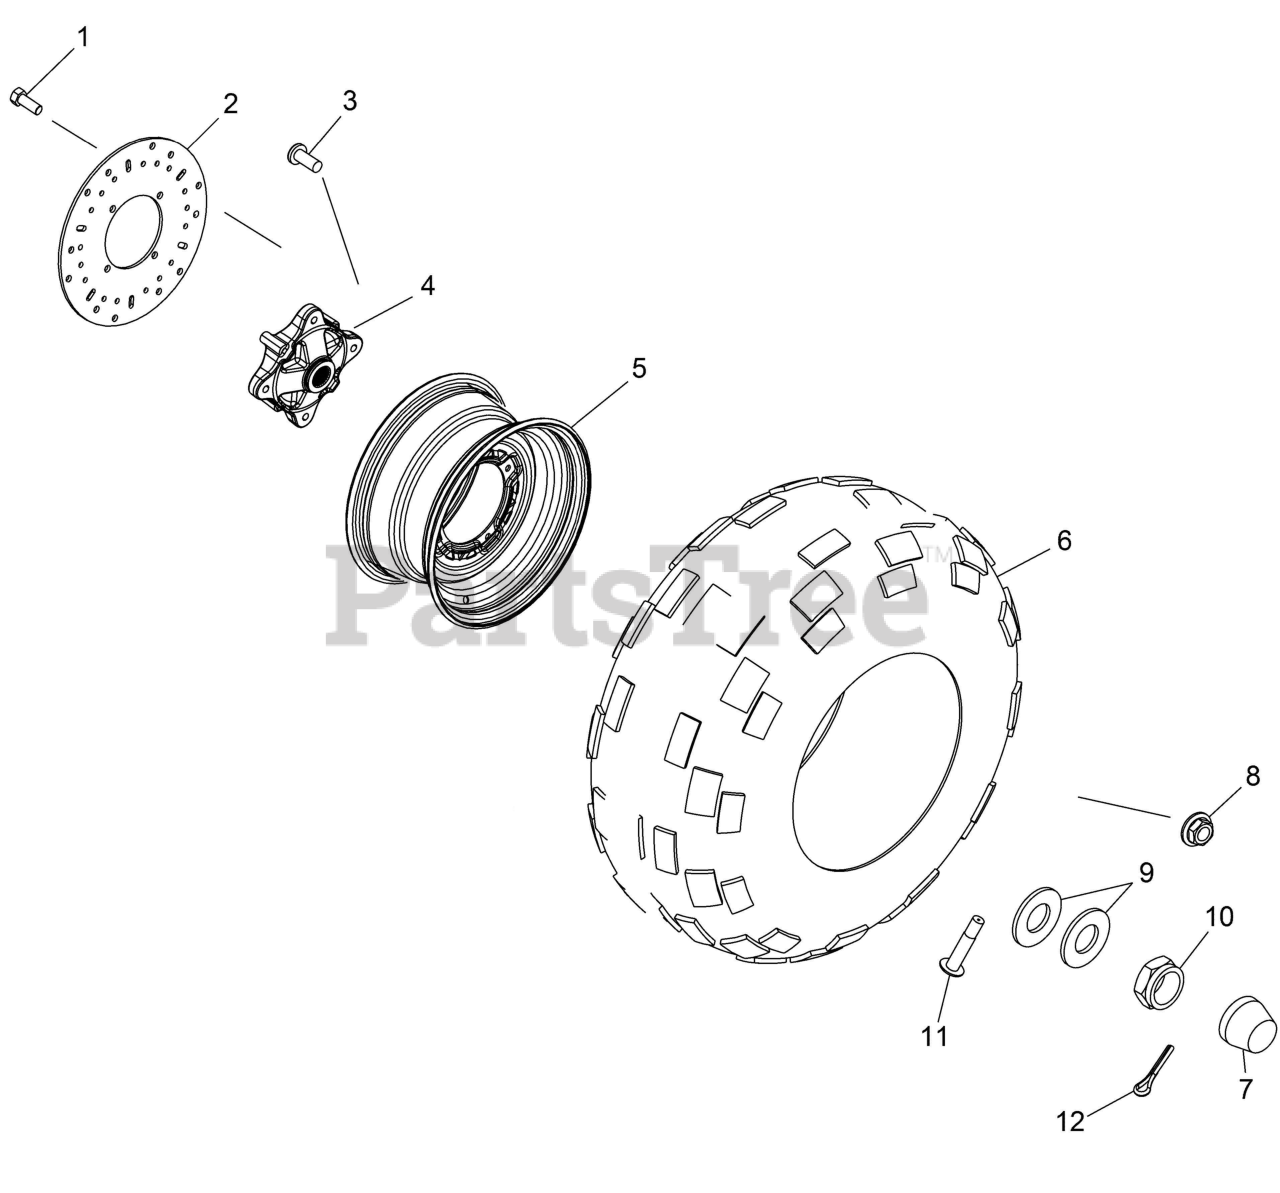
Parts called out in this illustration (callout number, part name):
1	SCR-M10X1.5X20,8.8 ZY3
2	DISC-BRAKE,REAR,8.625X.188
3	STUD-WHEEL,M12-1.5
4	HUB-WHEEL,REAR,MACH,BLK
5	WELD-RIM,RR,12X8,6"OFST,M.BLK
6	TIRE, REAR, 25X11-12
7	CAP, DUST
8	NUT-LUG,M12
9	WASHER, CONE
10	NUT-M18X1.5,CASTLE,ZINC/YELLOW
11	VALVE, RIM
12	PIN, COTTER
